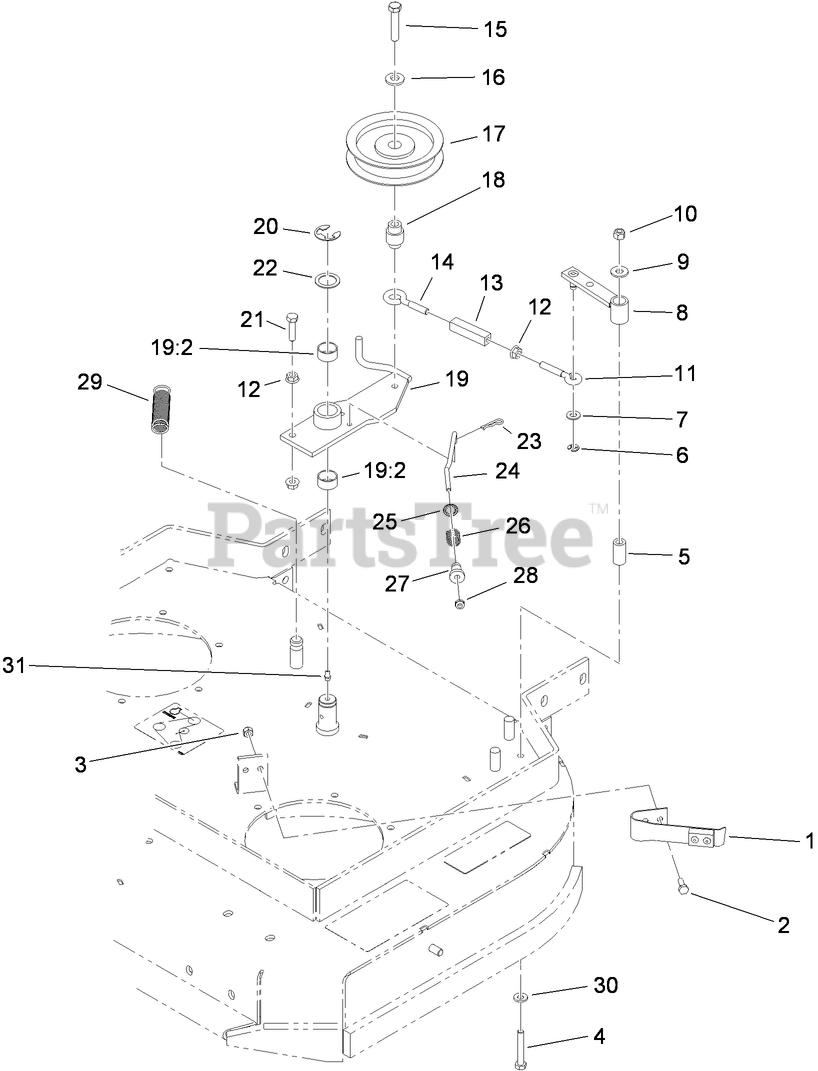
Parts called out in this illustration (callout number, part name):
1	PAD AND SPRING ASM
2	SCREW-HH
3	NUT-LOCK, NI
4	SCREW-HH
5	TUBE-PIVOT
6	RING-RETAINING, EXT
7	WASHER-PLAIN
8	ARM-ASSIST
9	WASHER-FLAT
10	NUT-LOCK, NI
11	EYEBOLT-THREAD, RH
12	NUT-HF
13	BODY-TURNBUCKLE
14	EYEBOLT-THREAD, LH
15	SCREW-HH
16	WASHER-BELLEVILLE
17	PULLEY-IDLER
18	BUSHING-ENGAGEMENT
19	Idler Arm ASM
19:2	SLEEVE-BEARING
20	RING-RETAINING, EXT
21	SCREW-HH
22	WASHER-SPINDLE
23	PIN-COTTER
24	ROD-BRAKE
25	RING-PUSH ON
26	SPRING-COMPRESSION
27	SPACER-FLANGED
28	NUT-LOCK, NI
29	SPRING-EXTENSION
30	WASHER-SPRING
31	FITTING-GREASE
